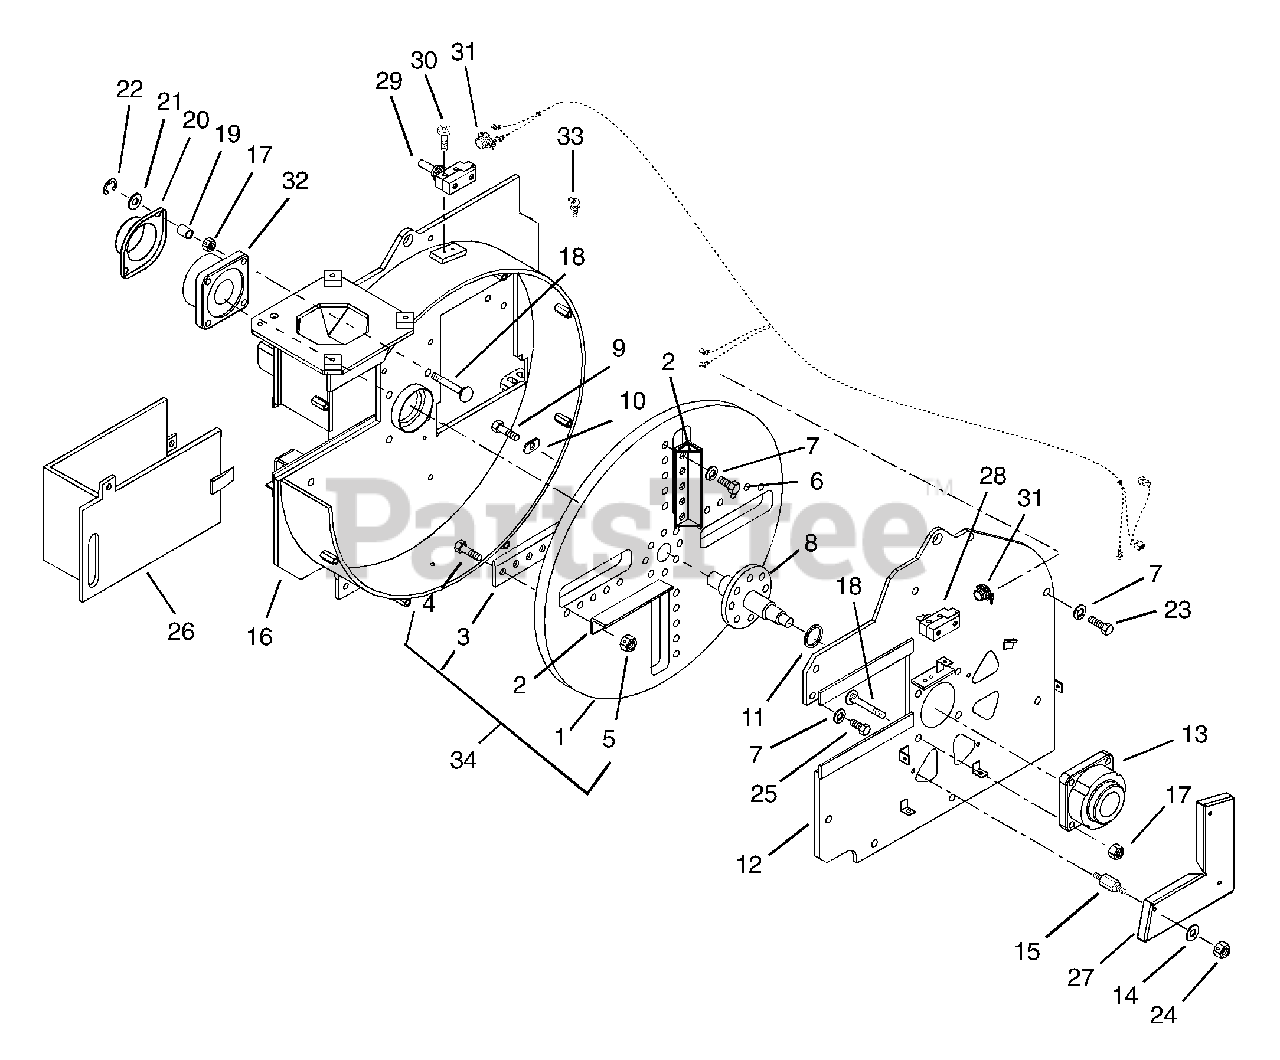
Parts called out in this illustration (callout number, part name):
1	Flywheel
2	Impeller Angle
4	Bolt-Flat Socket Head .50-13 x 3.00 Grade 8
5	Nut-Locking-Cone .50-13 Grade C
6	Bolt-Hex .50-13 x 1.25 Grade 5
7	Washer-Locking .50 x .125
8	Shaft Weldment
9	Bolt-Hex .62-11 x 2.25 Grade 8
10	Lock Tab
11	Shim-Flywheel Shaft
12	Housing-Chipper-Front Weldment
13	Bearing-Flange 2.00 Inner Diameter Expandable
14	Washer-Flat-Steel .438 x 1.00 x .083
15	Spacer-Screen
16	Rear Chipper Housing Weldment
17	Nut-Locking .62-18
18	Bolt-Rib Neck
20	Cover-Bearing
21	Washer-Flat-Steel .754 x 1.125 x .062
22	Ring-Retaining External .750 x .042
23	Bolt-Hex .50-13 x 1.75 Grade 5
24	Nut-Locking-Center .38-16
25	Bolt-Hex .50-13 x 1.00 Grade 5
26	Access Cover Weldment
27	Guard-Screen
30	Screw-Machine-Pen Head 6-32 x 1.50
31	Connector
32	Flange-Bearing
33	Fitting-Lube .25-28 x .256
34	Set-Chipper Knife
